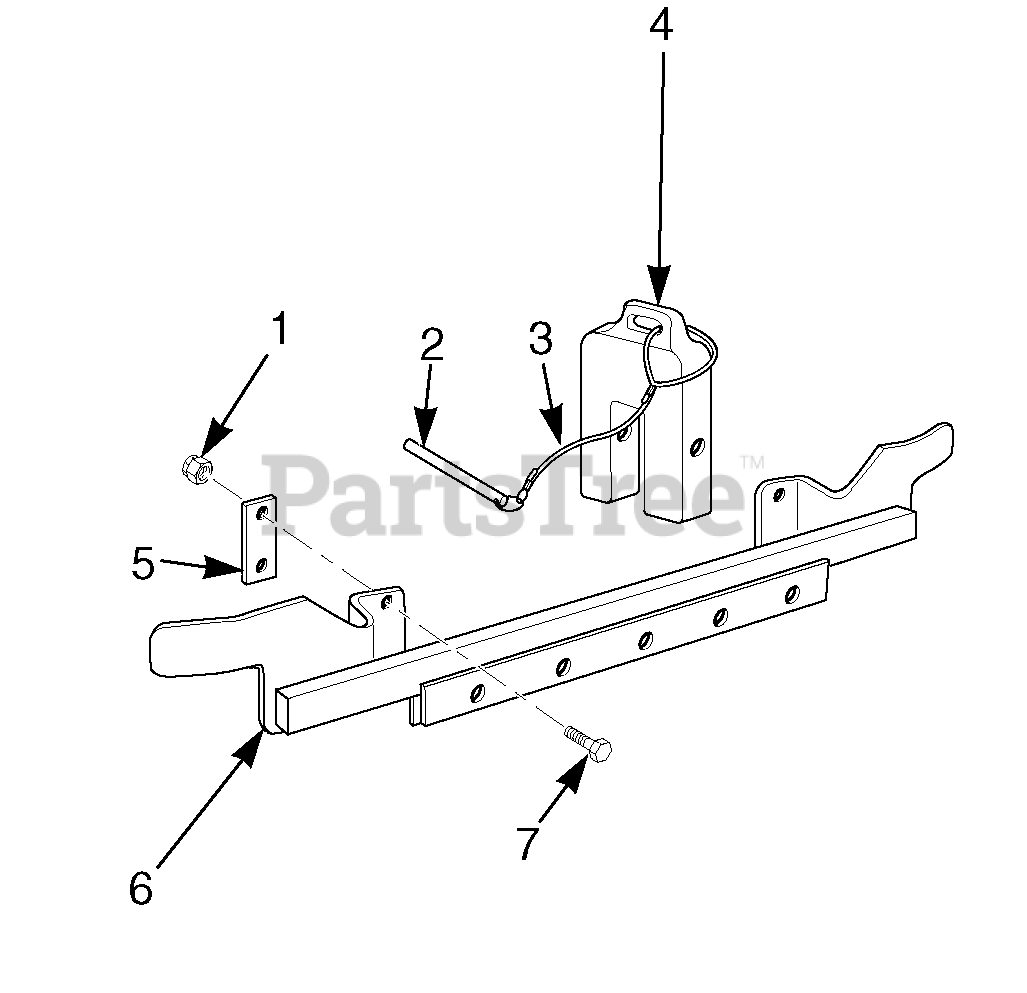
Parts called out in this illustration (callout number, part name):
1	Nut, Elastic Stop 3/8-16
2	Pin, 1/2 x 6-1/4"
3	Lanyard, Weight Pin
4	Weight Assembly
5	Clamp, Bar
6	Support Weldment, Front Weights
7	Bolt, Hex Head 3/8-16 x 1-1/2"
